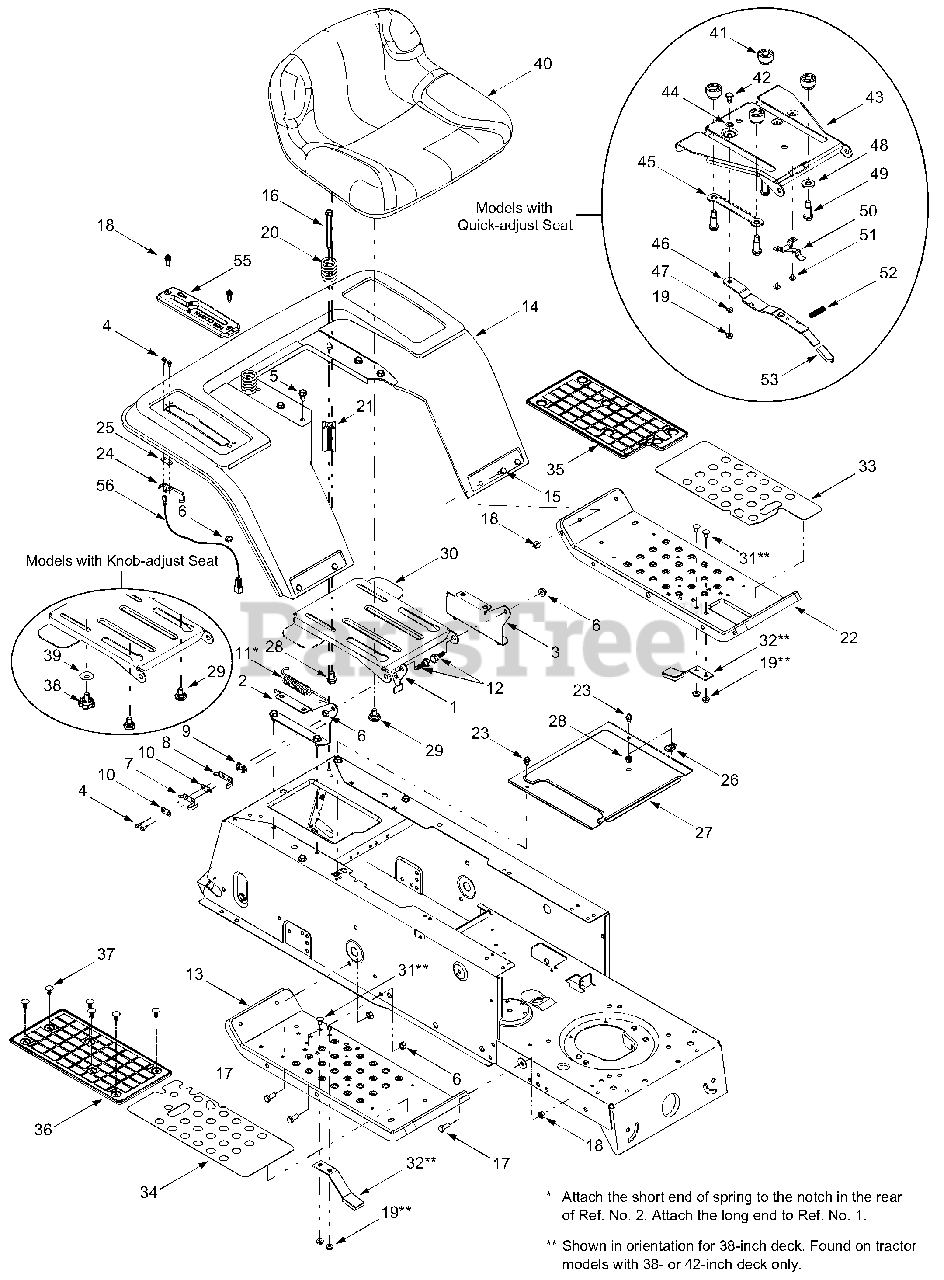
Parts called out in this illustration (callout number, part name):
1	Seat Lift Bracket
4	Self-tapping Screw, #8-18 x .50
5	Self-tapping Screw, 5/16-12 x .75
6	Lock Nut, 5/16-18
7	Outer Seat Spring Switch
8	Inner Seat Spring Switch
9	Insulator Plate Boss
10	Insulator Plate
11	Extension Spring, .75 x 5.31
12	Shoulder Screw, .437 x .286
16	Self-tapping Screw, 5/16-18 x 3.5
17	Hex Screw, 5/16-18 x .75
18	Self-tapping Screw, 1/4-20 x .75
19	Lock Nut, 1/4-20
20	Compression Spring, 1.314 x 1.8
21	Spacer
24	Spring Switch, Long
25	Insulator Nut Plate
26	U-Clip Nut, 1/4-20
28	Screw, 3/8-16 x .625
29	Shoulder Screw, .625 x .175, 3/8-16
31	Carriage Screw, 1/4-20 x .50
32	Blade Spindle Brake Assembly
33	LH Abrasive Foot Pad
34	RH Abrasive Foot Pad
35	LH Rubber Foot Pad
36	RH Rubber Foot Pad
37	Ratchet Clip, .250 Dia
38	Knob, 3/8-16 X .625
39	Bell Washer, .389 x 1.120 x .030
40	Low Back Seat, Black
41	Spacer
42	Shoulder Screw, .340
45	Seat Select Bracket
47	Spring Washer
48	Flat Washer, .531 x 1.062 x .134
49	Shoulder Screw, .50 x .925, 3/8-16
50	Seat Stop
51	Screw, #10-16 x .375
52	Compression Spring
54	Compression Spring, 1.314 x 2.55
55	Speed Index Bracket
56	Wire Extension, Reverse
